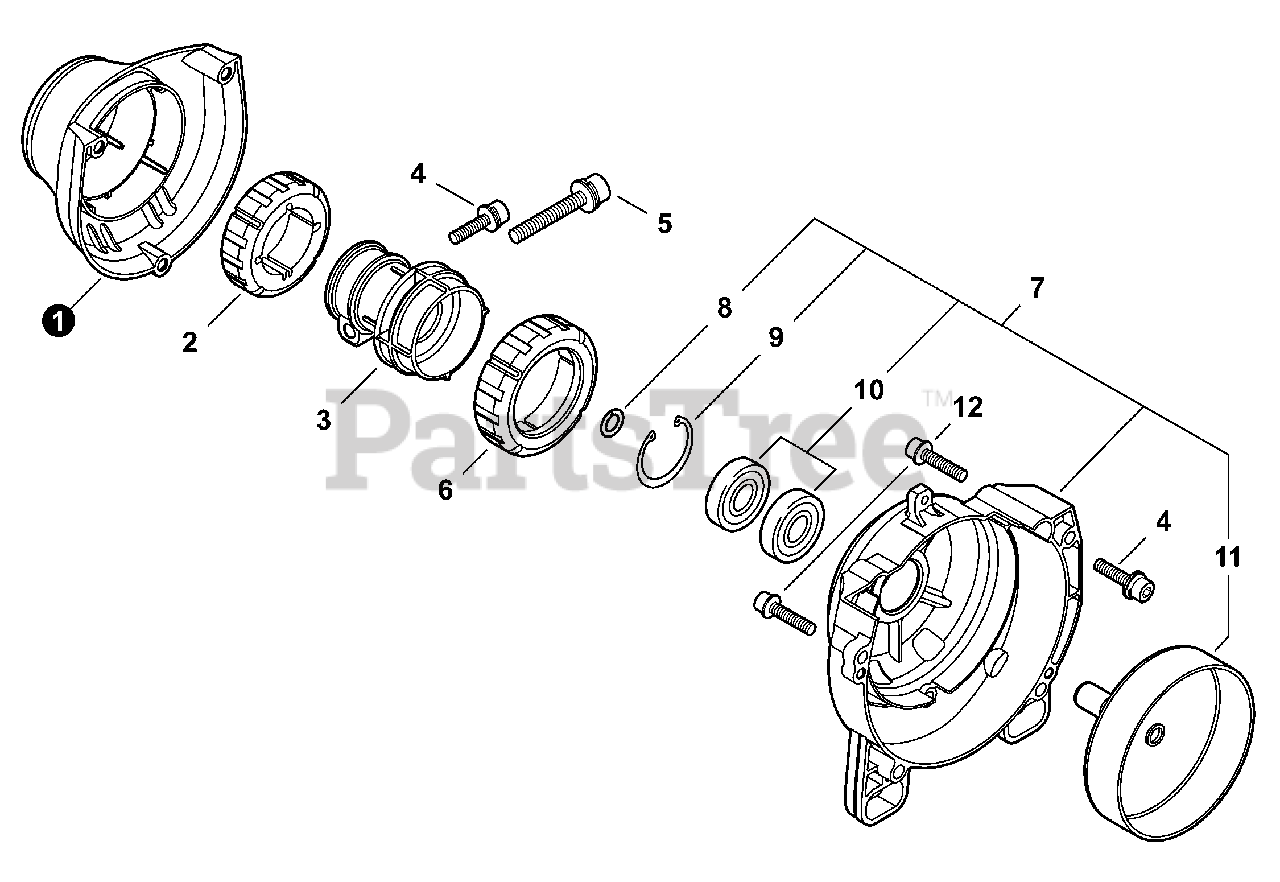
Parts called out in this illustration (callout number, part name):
1	COVER, CUSHION
2	HOLDER, FRONT CUSHION
3	CUSHION
4	BOLT M5×16
5	BOLT M6×28
6	HOLDER, REAR CUSHION
7	COVER ASSY, FAN
8	RING, SNAP 12
9	RING, SNAP Ø28
10	BEARING, BALL 6001 DDU C3
11	DRUM, CLUTCH
12	BOLT M5×20
